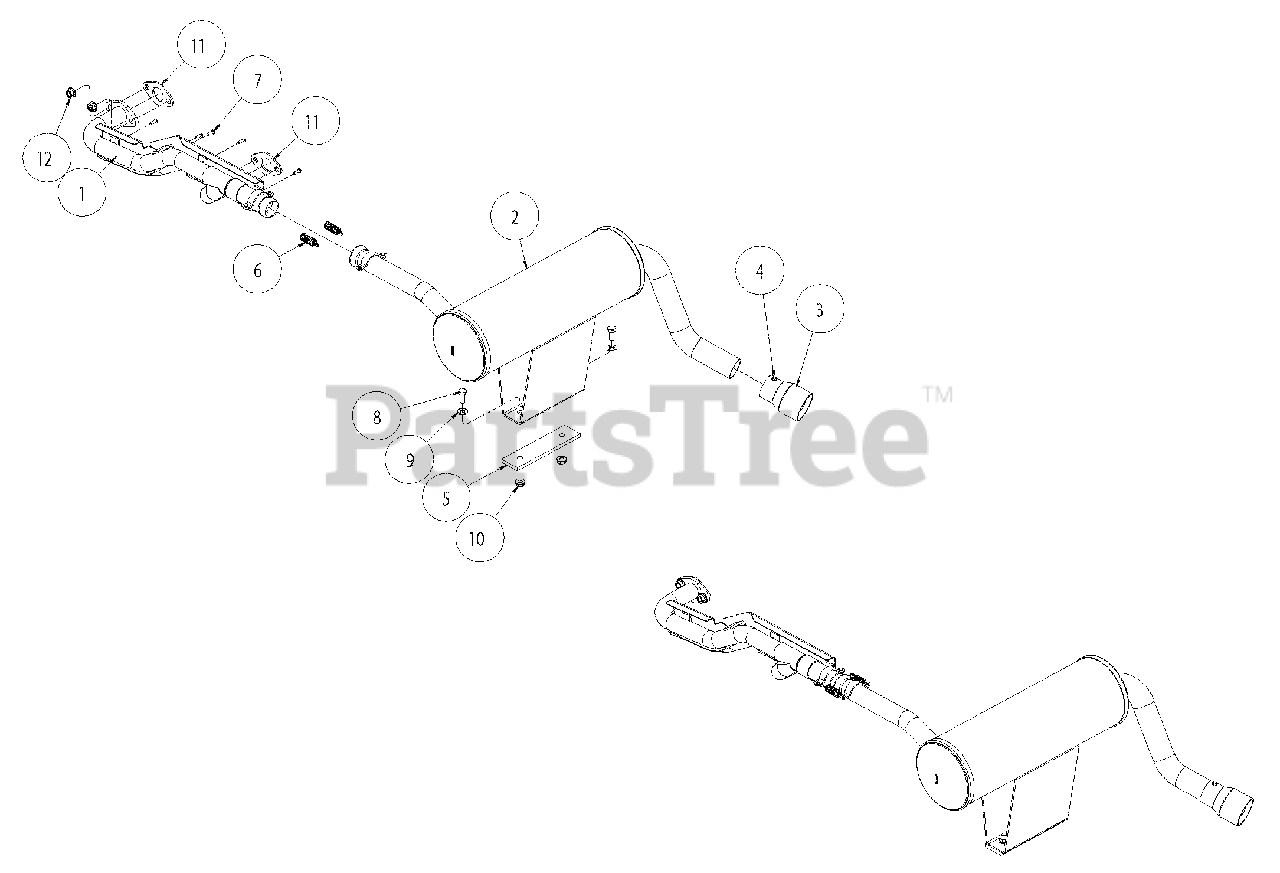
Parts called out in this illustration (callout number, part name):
1	ENGINE MANIFOLD, SUBARU
2	MUFFLER, SUBARA
3	SPARK ARRESTER WITH SCREW
4	SCREW HEX SLT 8-18X1/2 PLT
5	SHIM, MUFFLER MOUNTING
6	SPRING EXT. .5ODX1.68LGX.08W
7	SCREW, HEX #8 X 1/2 SELF TAP
8	HHCS 5/16-18 X 3/4 GR5 YELLOW DI
9	WASHER, FLAT 5/16-18 FLG
10	NUT HEX LOCK 5/16-18 FLG
11	GASKET, SUBARU
12	NUT HEX FLANGE M8X1.25 PLT
